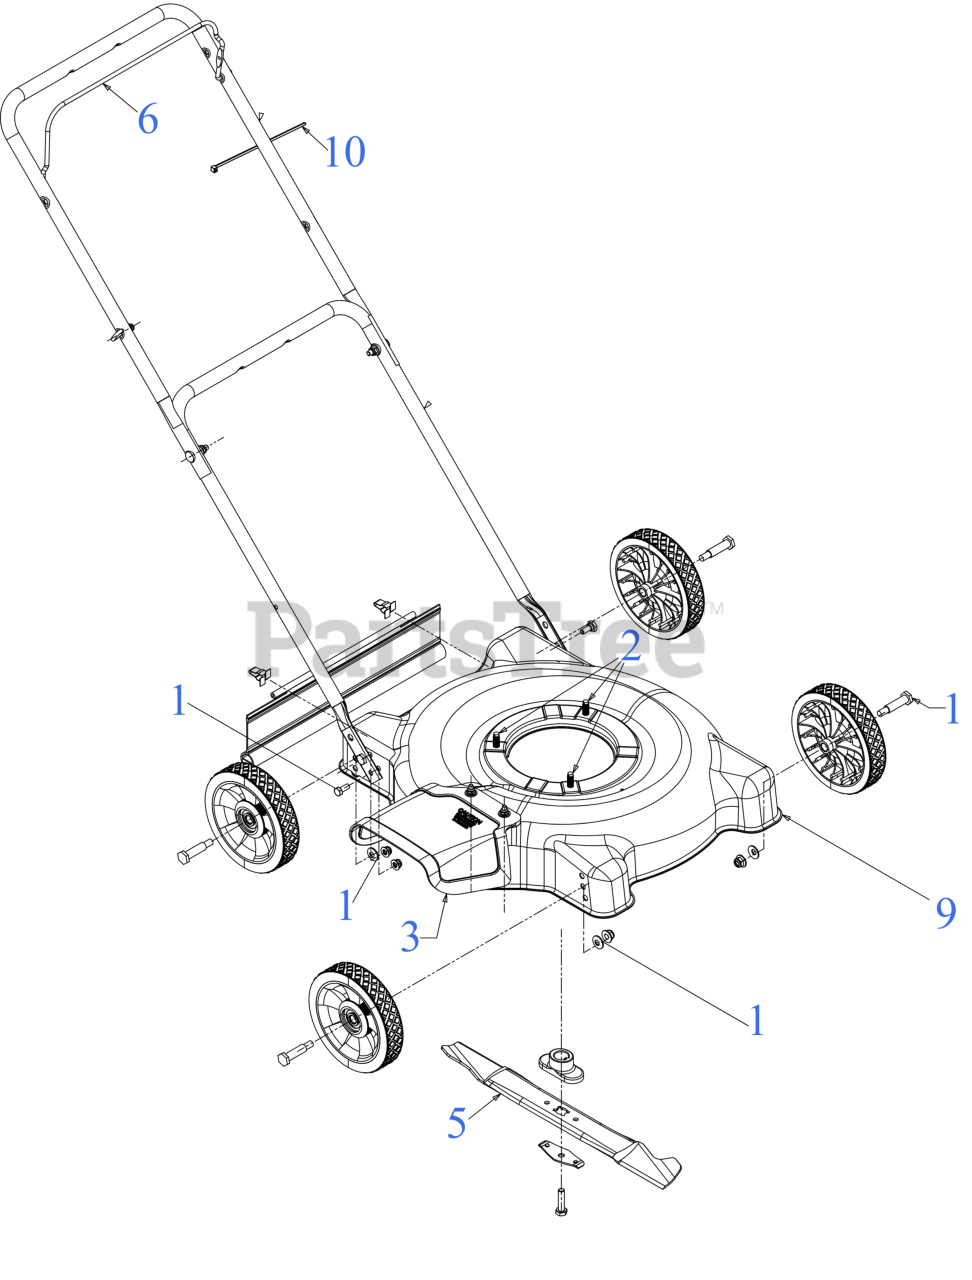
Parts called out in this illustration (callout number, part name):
1	SCREWPACK ASSEMBLY
2	SCREW 3/8-16 x 1
3	20" FIXED DISCHARGE CHUTE
5	20" BLADE
10	7" CABLE TIE
